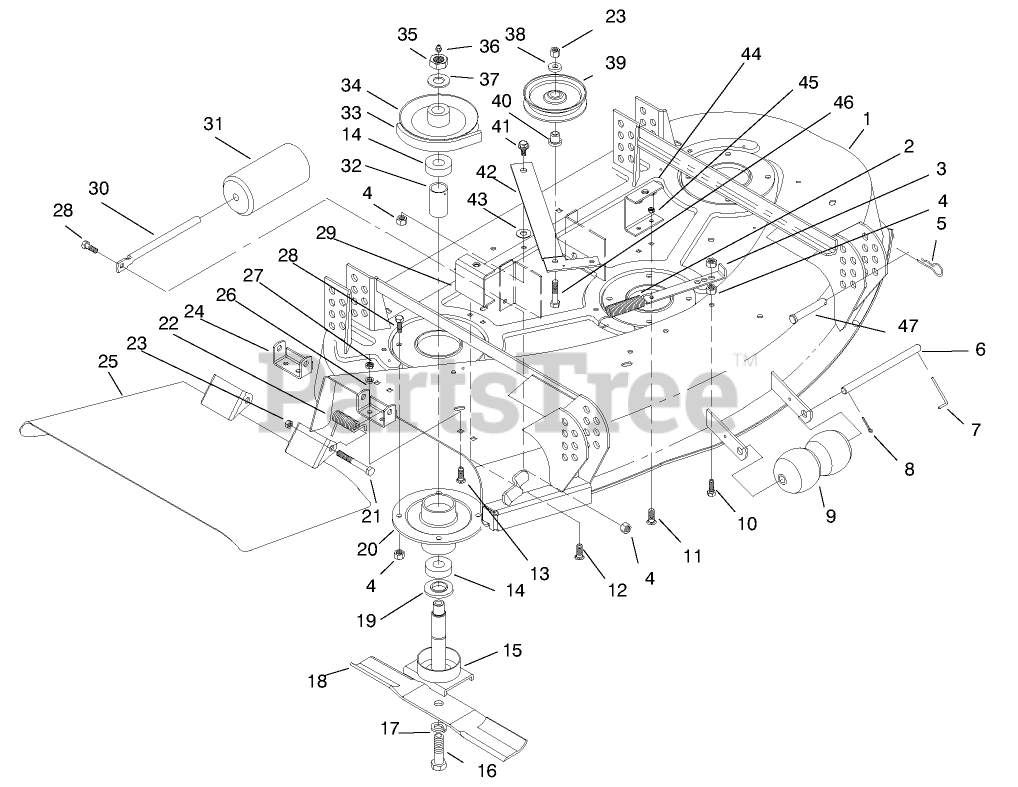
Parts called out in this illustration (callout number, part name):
2	SPRING-EXTENSION, DECK
3	Anchor-Deck Spring
4	NUT-LOCK, CONE
5	PIN-HAIR
6	SHAFT-ROLLER
7	PIN-SPECIAL
8	PIN-COTTER
9	ROLLER
10	SCREW-HH
11	SCREW-CARR
12	SCREW-CARR
13	SCREW-CARR
14	BEARING-BALL
15	SHAFT-SPINDLE
16	SCREW-BLADE
17	WASHER-LOCK
18	Blade-Recycler
19	SPACER-SPINDLE
20	HOUSING-SPINDLE
21	SCREW-HH
22	SPRING
23	NUT-HEX
24	BRACKET-PIVOT
25	Grass Deflector
28	SCREW-HH
29	Bracket-Cover RH
30	ROD-ROLLER
31	ROLLER-DECK
32	SPACER-BEARING
33	V-BELT-DECK
34	PULLEY-DECK
35	NUT-HEX
36	FITTING-GREASE
37	WASHER
38	WASHER-FLAT
39	PULLEY-IDLER
40	BUSHING-PULLEY
41	SCREW-SHOULDER
42	Lever-Deck
43	WASHER
44	Bracket-Cover LH
45	NUT-LOCK, NI
46	SCREW-HH
47	PIN-CLEVIS
